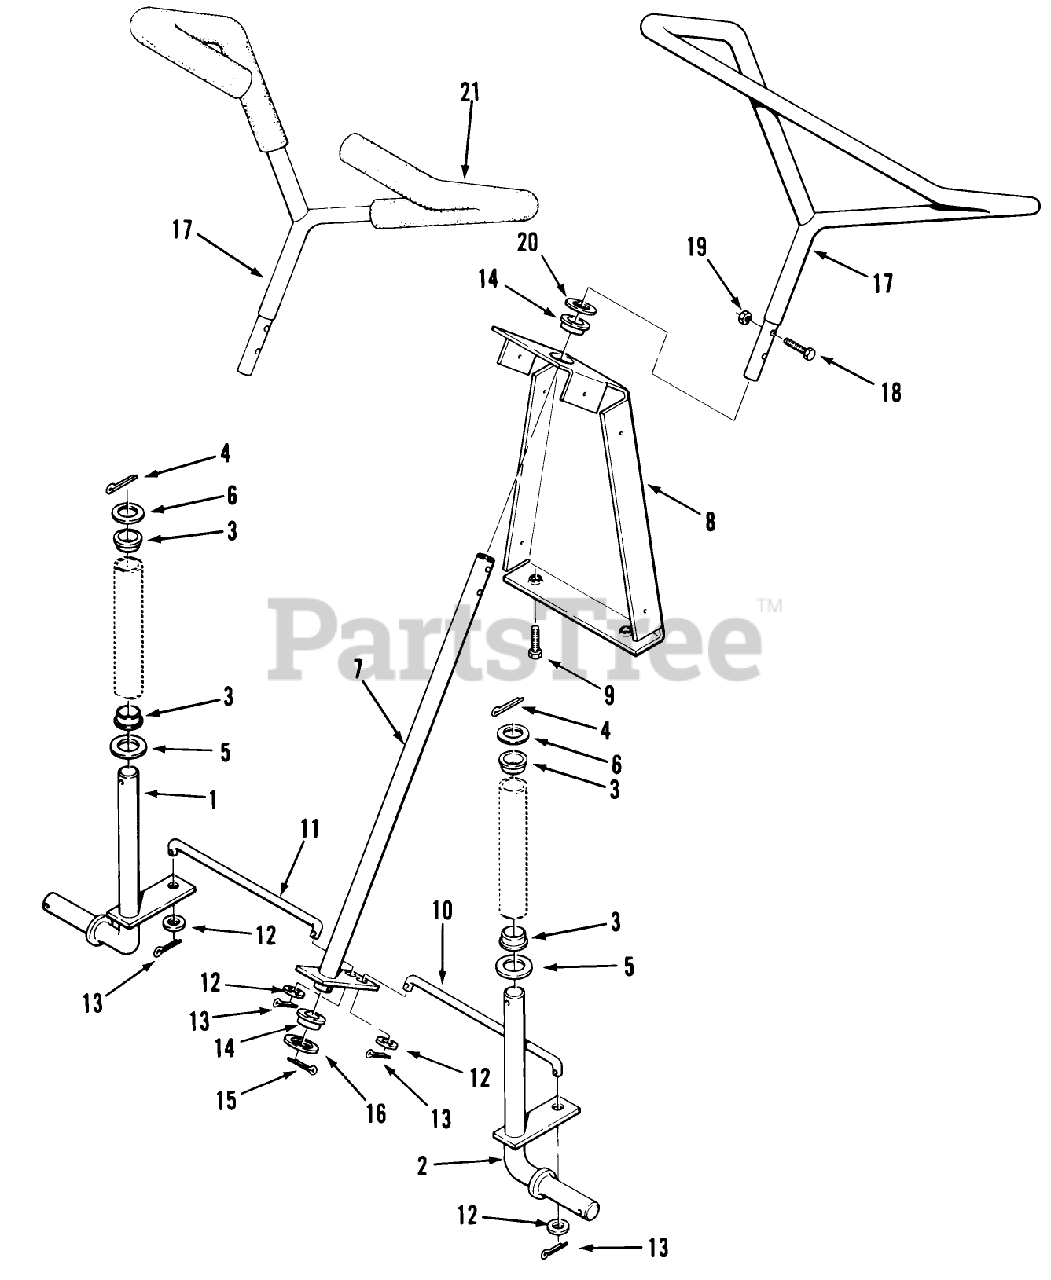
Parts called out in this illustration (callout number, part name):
1	SPINDLE ASSY RH *R
2	SPINDLE ASSY LH *R
3	BUSHING
6	WASHER
9	Screw
12	Washer-3/8
14	BEARING
16	WASHER-FLAT
17	STEERING WHEEL
